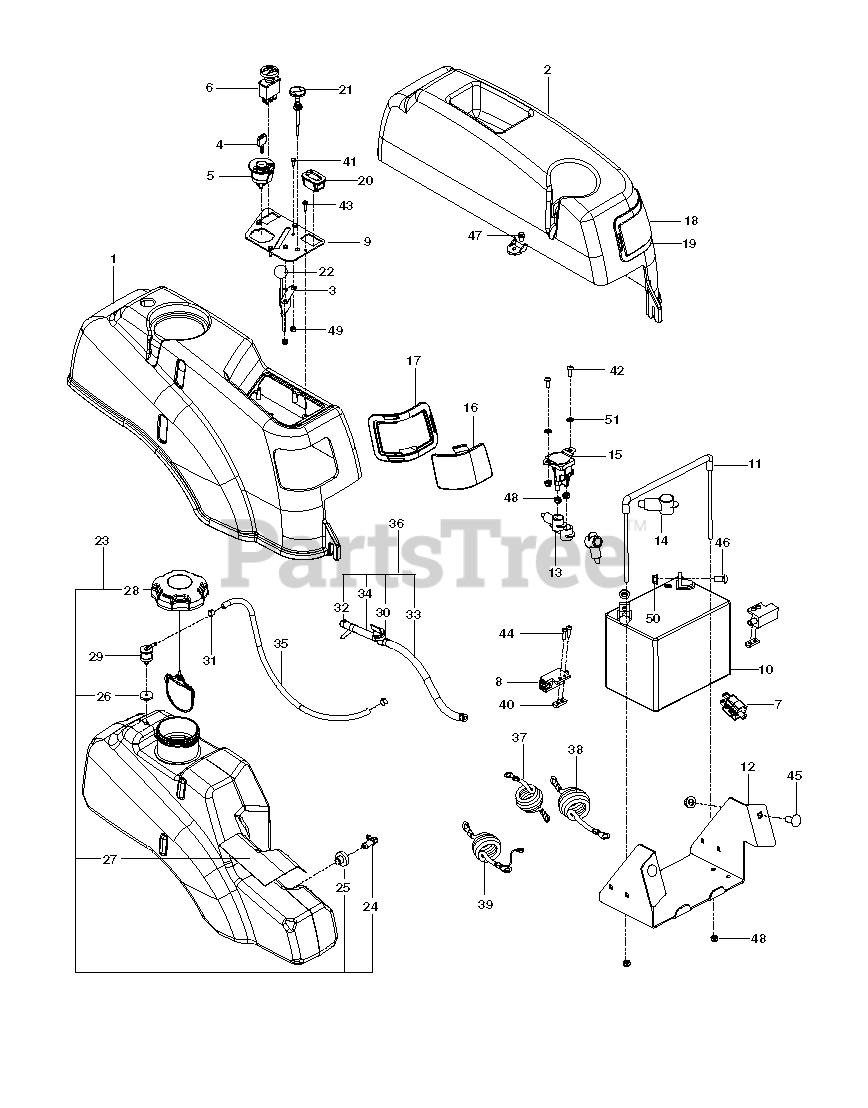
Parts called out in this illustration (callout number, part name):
1	FENDER RT, GRAY
2	FENDER, LT
3	THROTTLE CABLE
4	KEY
5	RP IGNITION SWITCH
6	SWITCH.PTO
7	SWITCH, BRAKE 3P
8	SWITCH INTERLOCKT
9	CONSOLE.PLATE.BLACK
10	BATTERY, 12 V 330 AMP
11	BATTERY TIE DOWN ASSEMBLY
12	BOX, BATTERY, BLACK
13	TERMINAL COVER-SM
16	LENS, COLORED RIGHT
17	RT HEADLIGHT RIM GREY
18	LENS, COLORED LEFT
19	LEFT HEADLIGHT RIM GREY
20	RP GUAGE.SRVCMNDR.HRMTR.
21	CHOKE CABLE
22	KNOB.ROUND.BALL.BLACK
23	TANK.FUEL.ASSEMBLY.LARGE
24	STEM, FUEL TANK
25	RUBBER GROMMET
26	GROMMET, CHECK VALVE
27	SHIELD, HEAT
28	CAP, FUEL
29	VALVE.FUEL.CHECK
30	FUEL VALVE
31	CLAMP, HOSE
32	HOSE CLAMP
33	GAS LINE 10"
34	FUEL LINE 14"
35	HOSE, VAPOR 3/16 X 48"
36	FUEL LINE ASSY
37	CABLE POSITIVE, LONG
38	BATTERY CABLE, NEGATIVE
39	CABLE POSITIVE LONG W/LEAD
40	TAPPED PLATE
41	HCS #10-24 X 1/2
42	SCR 1/4-20 X 5/8 BTN SKT HD ZD
43	SCR #10-12X3/4 HEX WAS HD ZD
44	SCR #10-24 X .75 SKT HD BLK
45	RHSNB 3/8C X 1
46	BOLT 5/16C X 3/4" CARRIAGE
47	BOLT 1/4-20 X 1/2 HWST
48	RP_NUT 1/4-20 NYLOC
49	NUT 10-24 NYLOC
50	5/16-18 NYLOC FLANGE NUT
51	WASHER 1/4 INT TOOTH
